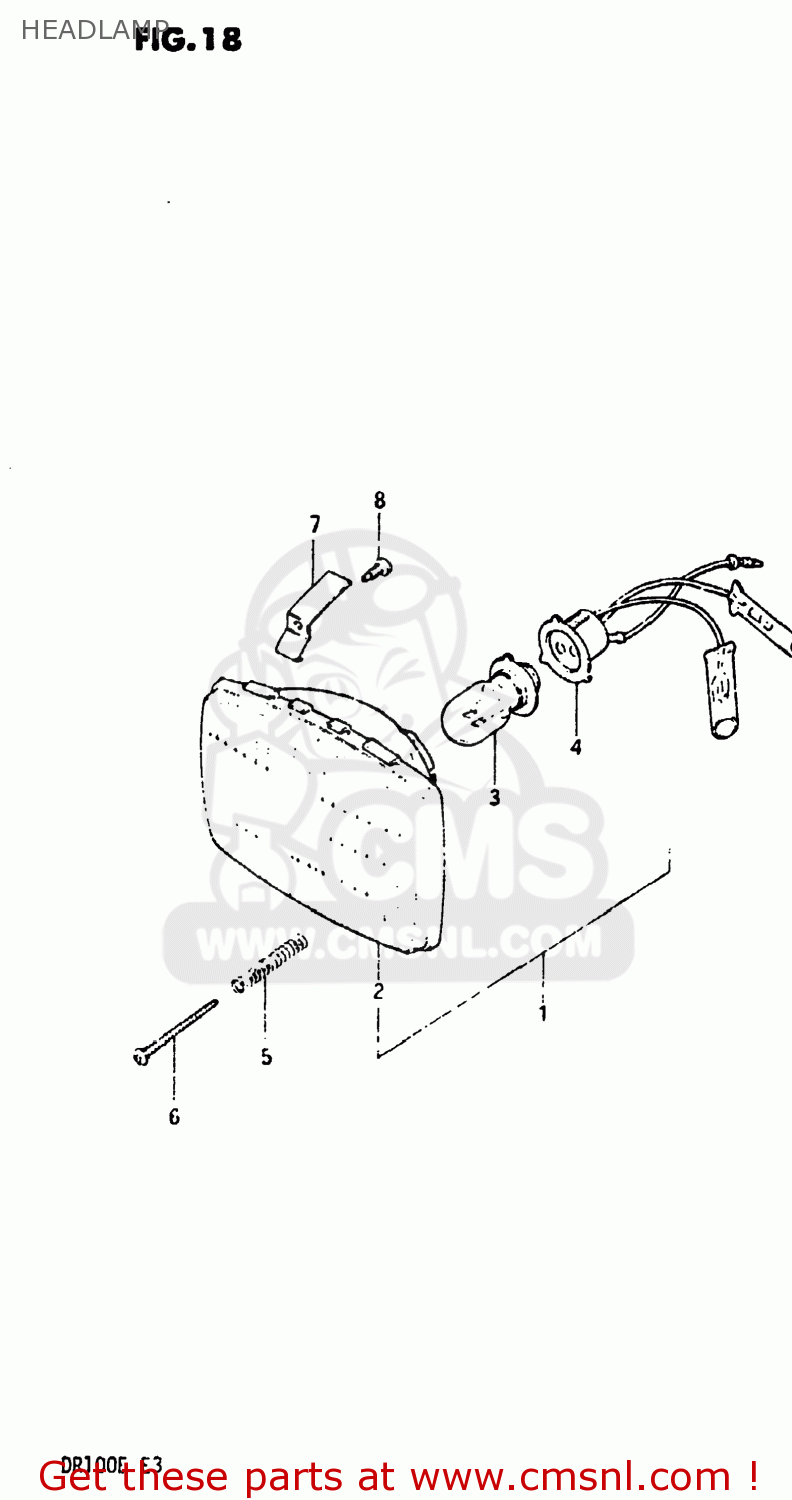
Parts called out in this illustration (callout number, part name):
1	HEADLAMP ASSEMBLY
2	LAMP UNIT
3	BULB(6V15/15W/STANLEY,A3598HA)
4	SOCKET,HEADLAMP
5	SPRING,HEAD LAMP ADJUSTER
6	SCREW,HEADLAMP ADJUST
7	SPRING
8	SPRING,HEADLAMP ADJUST
